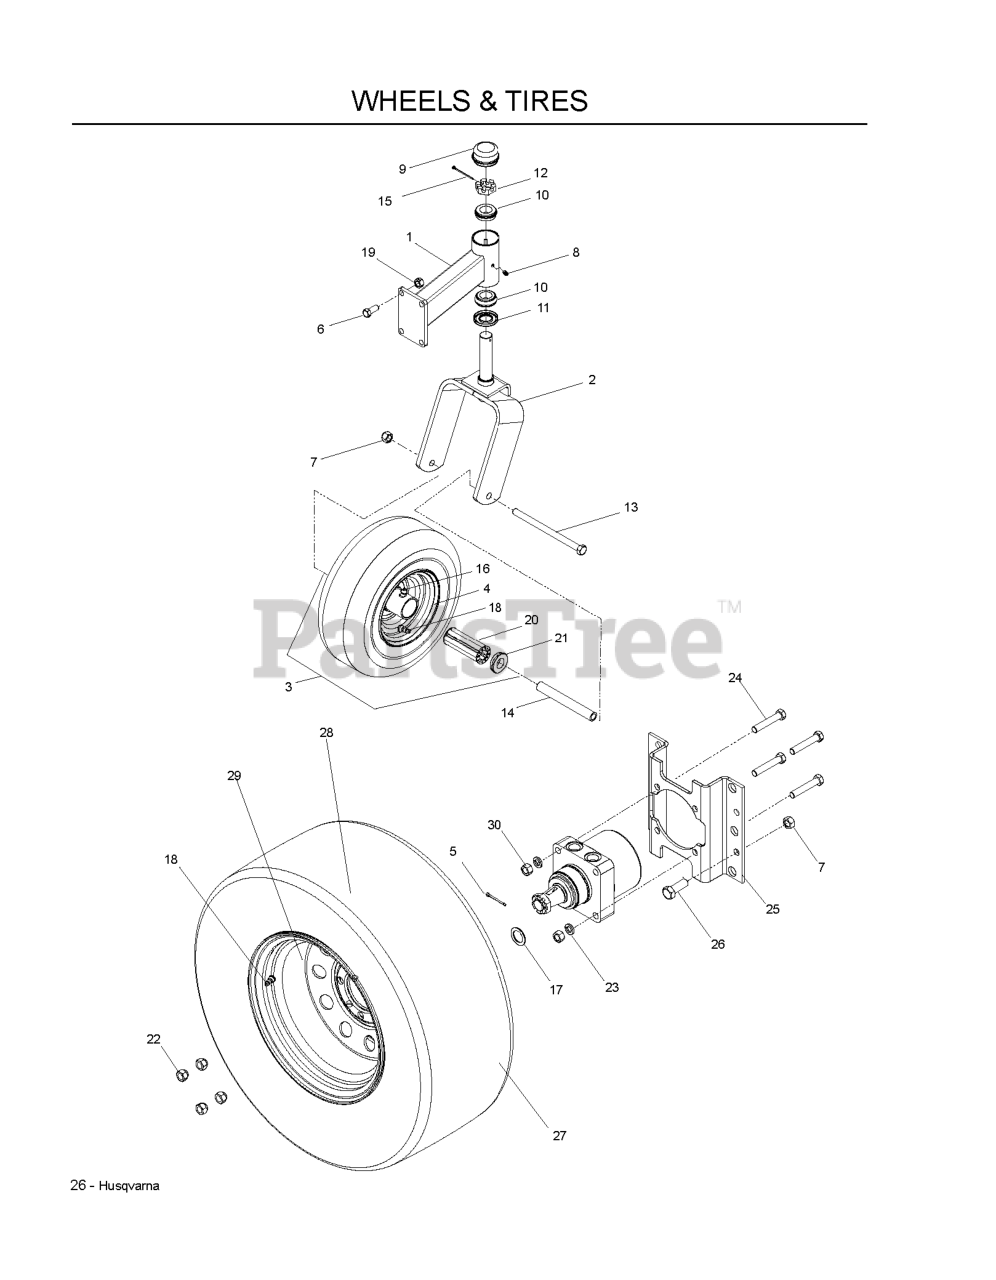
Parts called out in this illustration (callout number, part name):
1	CASTER ARM, ORG
2	CASTER YOKE ORANGE
3	TIRE.ASSEM.13X5-6.SMOOTH.SILVE
4	RIM
5	COTTER PIN
6	HCS 7/16-14 X 1 GR 5 ZD
7	NUT 1/2-13 HEX NYLOC ZD
9	GREASE CAP
10	TAPERED ROLLER BRG
12	NUT 1"C HEX SLOTTED
13	SCREW 1/2C X 7 1/2 HEX CAP
14	SPACER, CASTER
15	COTTER PIN 1/8 X 2
16	ZERK 1/8 NPT
17	MACHINE BUSHING
18	VALVE STEM TR-412
19	NUT 7/16C CENTERLOCK
20	ROLLER BEARING
21	BEARING RETAINER
22	LUG NUT 1/2F
23	WASHER 1/2" SPLIT LOCK
24	HCS 1/2C X 2 3/4
25	MOTOR STANDOFF
26	HCS 1/2C X 1 1/4 SERRATED HEAD
27	WHEEL/TIRE.ASM.23X9.5-12.GREY
28	TIRE.TURF.MASTER.23X9.5-12
29	RIM, 12 X 7, 1" NEG OFFSET
30	NUT HEX 1/2
